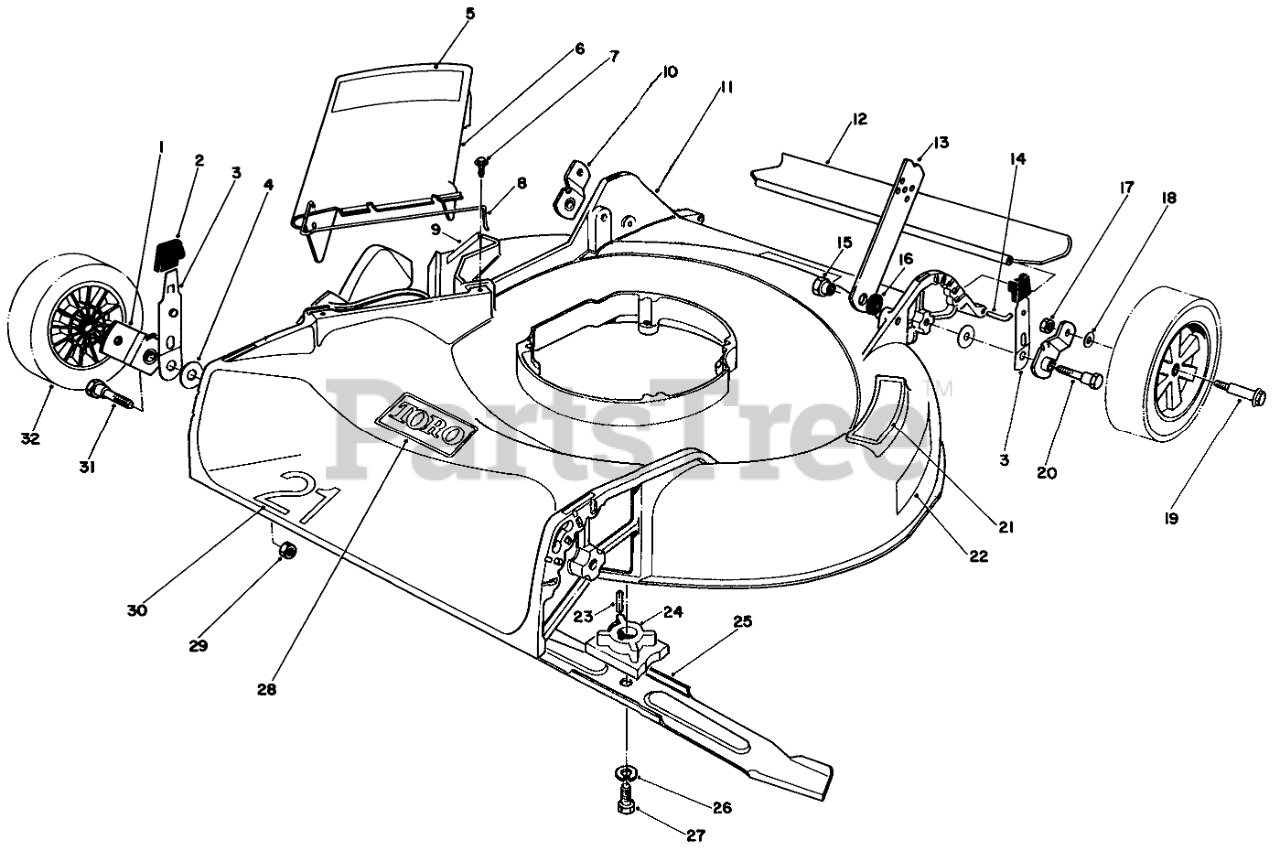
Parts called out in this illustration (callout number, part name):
1	Pivot Arm
2	KNOB-ARM
3	SPRING ARM ASM
4	WASHER-PIVOT
5	Decal-Danger
6	Deflector Assembly (Incl.Ref. #5 & 8)
7	Screw w/washer
8	SPRING HINGE
9	Decal-Danger
10	Pivot Arm
11	HOUSING/DECAL
12	REAR SAFETY SHIELD 21
13	HANDLE LATCH
14	SHIELD ROD
15	Pivot Nut
16	Spacer-Handle Latch
17	Nut
18	WASHER
19	Bolt-Wheel
20	PIVOT SCREW
21	STEP PAD DECAL
22	Decal-Step Pad
23	KEY-SQUARE
24	Blade Retainer
25	Blade
26	WASHER-LOCK
27	SCREW-HH
28	Decal Tow
29	NUT-LOCK, NI
30	Decal-21"
31	PIVOT SCREW
32	Wheel & Tire Assembly
